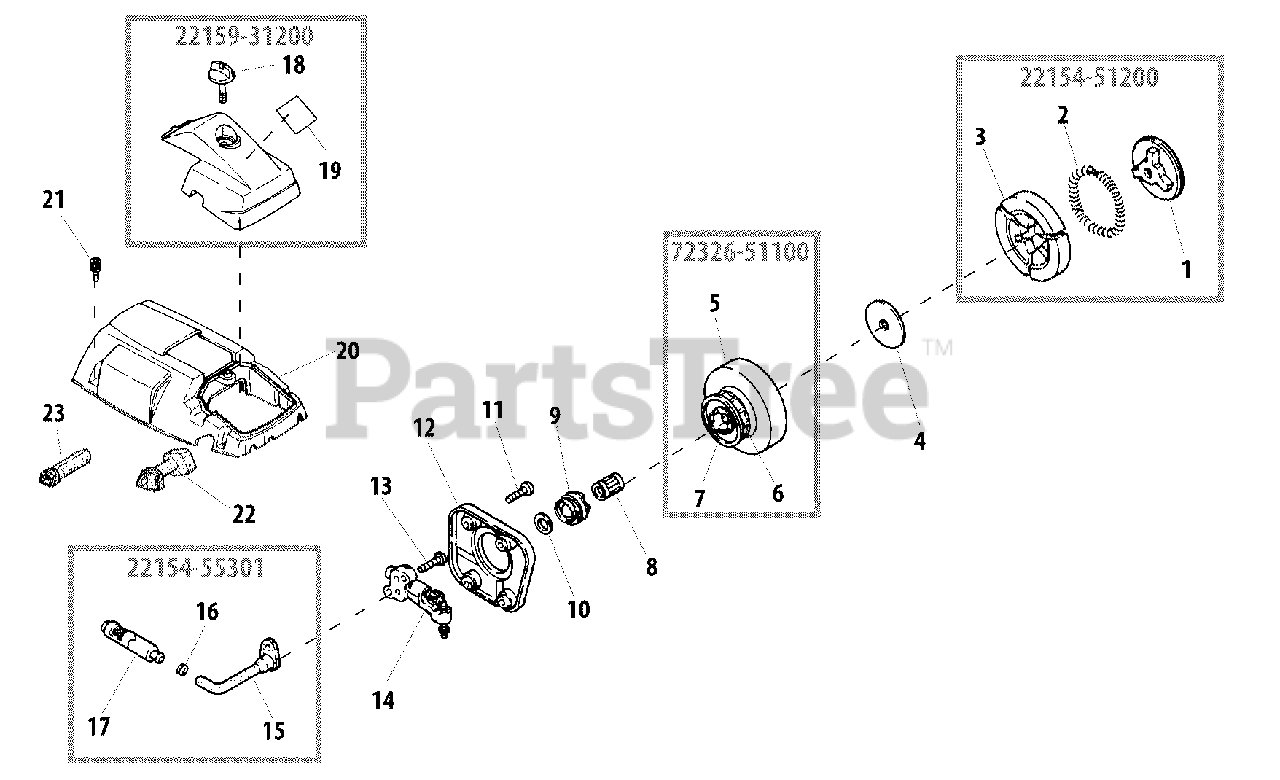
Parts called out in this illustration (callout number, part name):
1	HUB, CLUTCH - OUTER
2	SPRING, CLUTCH
3	SHOE, CLUTCH
4	HUB, CLUTCH - INNER
5	DRUM, CLUTCH
6	SPROCKET, RIM
7	COVER
8	BEARING, NEEDLE
9	GEAR
10	WASHER, THRUST
11	SCREW - 4X12
12	COVER, PUMP
13	SCREW - 4X12
14	AUTO-OILER ASSY
15	PIPE - OIL
16	CLIP
17	FILTER, OIL
18	THUMBSCREW
19	LABEL - CAUTION
20	COVER, ENGINE
21	SCREW - 4X16
22	GROMMET (EPA/CARB)
23	GROMMET
22154-51200	CLUTCH ASSY
22154-55301	OIL FILTER ASSY
22159-31200	AIR FILTER COVER ASSY
72326-51100	CLUTCH DRUM ASSY
